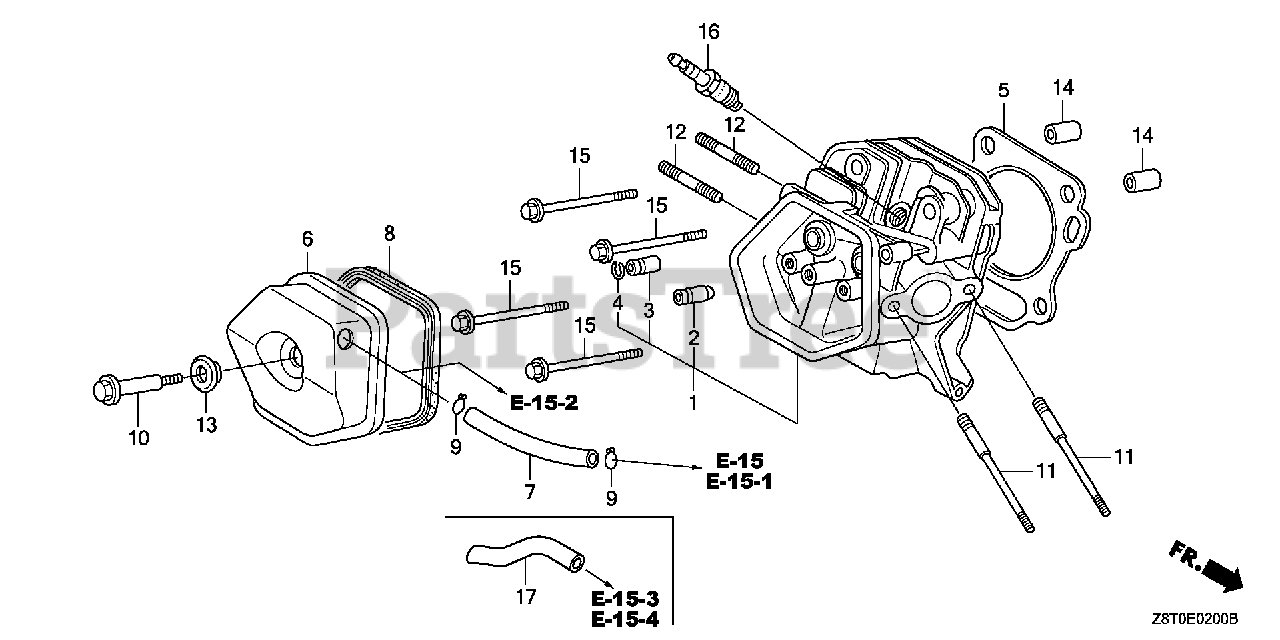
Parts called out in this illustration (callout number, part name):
1	CYLINDER HEAD
2	GUIDE, VALVE (OS)
3	GUIDE, EX. VALVE (OS)
4	CLIP, VALVE GUIDE
5	GASKET, CYLINDER HEAD (NIPPON LEAKLESS)
6	COVER, HEAD
6	COVER, CYLINDER HEAD
8	GASKET, CYLINDER HEAD COVER
10	BOLT, HEAD COVER
11	BOLT, STUD (8X131.5)
12	BOLT 2, STUD (8X32)
13	WASHER, HEAD COVER
14	PIN A, DOWEL (12X20)
15	BOLT, FLANGE (10X80)
16	SPARK PLUG (BPR5ES) (NGK)
16	SPARK PLUG (W16EPR-U) (DENSO)
16	SPARK PLUG (BPR6ES) (NGK)
16	SPARK PLUG (W20EPR-U) (DENSO)
17	TUBE, BREATHER
